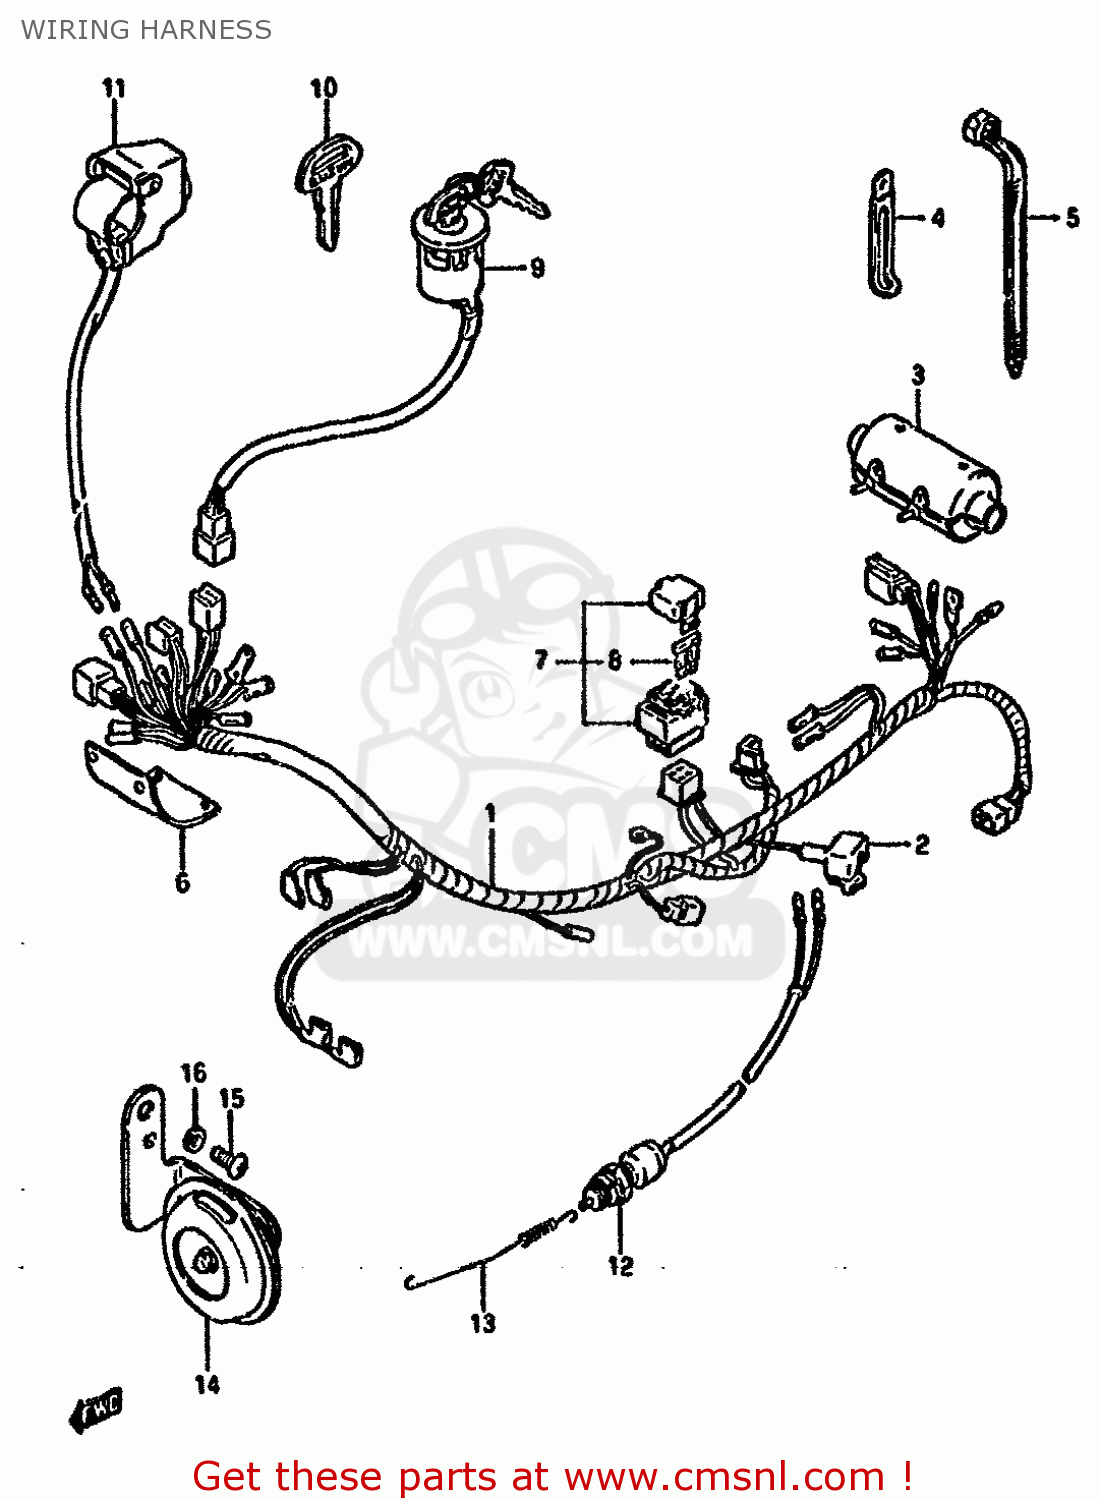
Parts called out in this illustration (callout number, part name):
1	HARNESS,WIRING
2	CAP,BATTERY TERMINAL
3	BOOT,WIRING HARNESS
4	CLAMP
5	CLAMP(L:125)
6	BOOT,WIRING HARNESS
7	BOX ASSY,FUSE
8	FUSE(15A)
9	SWITCH ASSEMBLY,IGNITION
10	KEY,BLANK
11	SWITCH ASSY,ENGINE STOP
12	SWITCH ASSY,STOP LAMP
13	SPRING
14	HORN ASSY
15	SCREW
16	WASHER,LOCK
